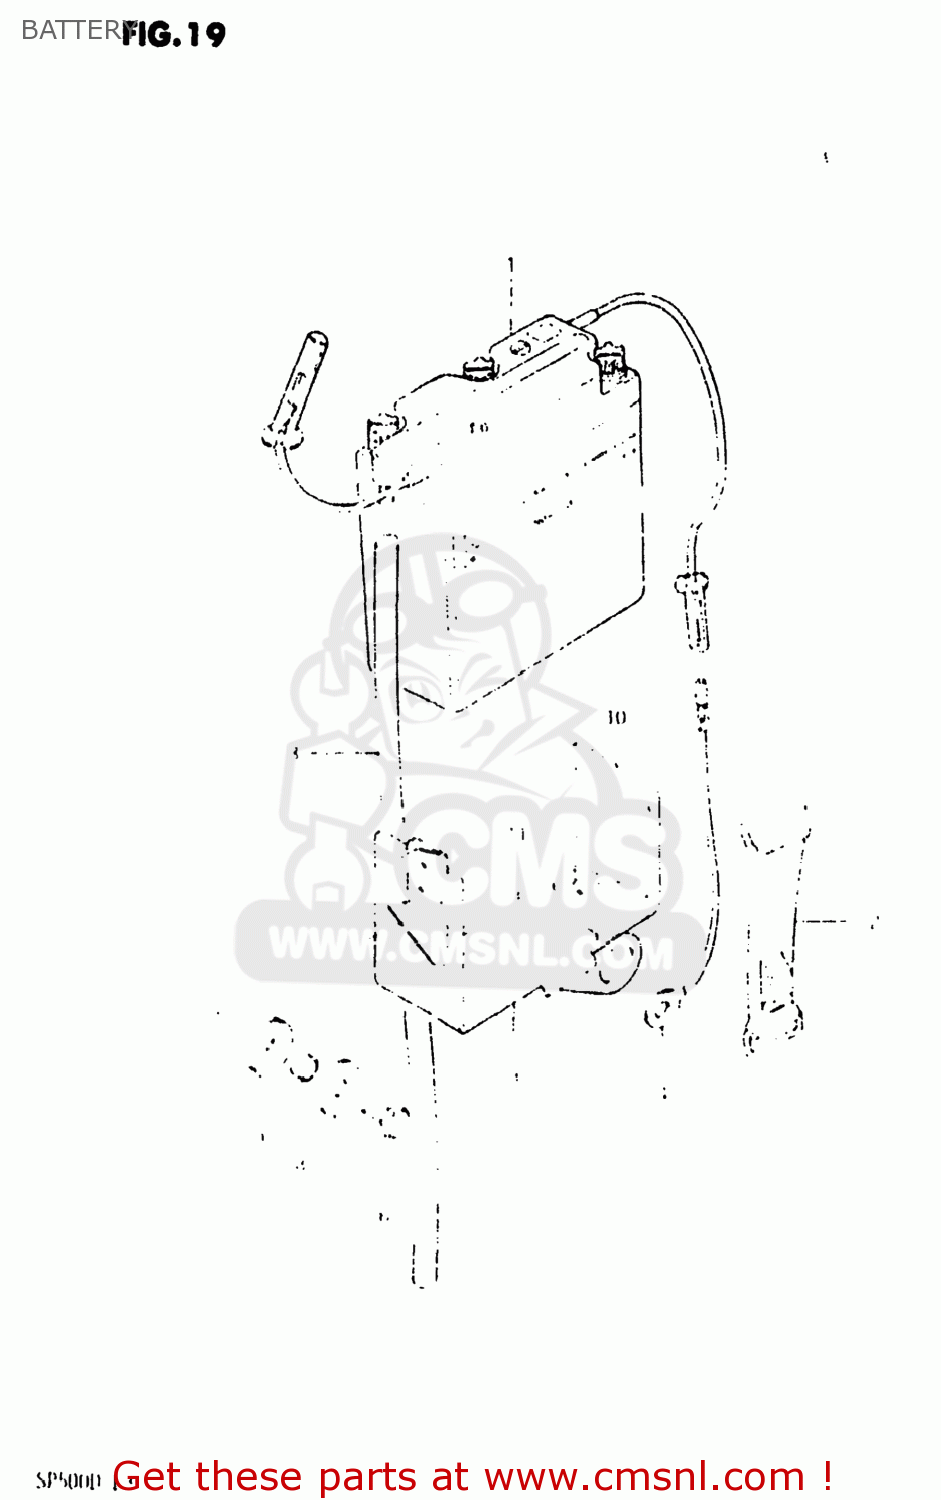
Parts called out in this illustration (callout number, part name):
1	BATTERY ASSEMBLY
2	CUSHION,BATTERY
3	HOSE,BATTERY EXHAUST
4	LEAD WIRE
5	HOLDER,BATTERY
6	BOLT, UPPER
7	WASHER (6.5X20X1.2)
8	SPACER(6.1X9X7.5)
9	CUSHION
10	PROTECTOR,BATTERY
11	PROTECTOR,BATTERY
